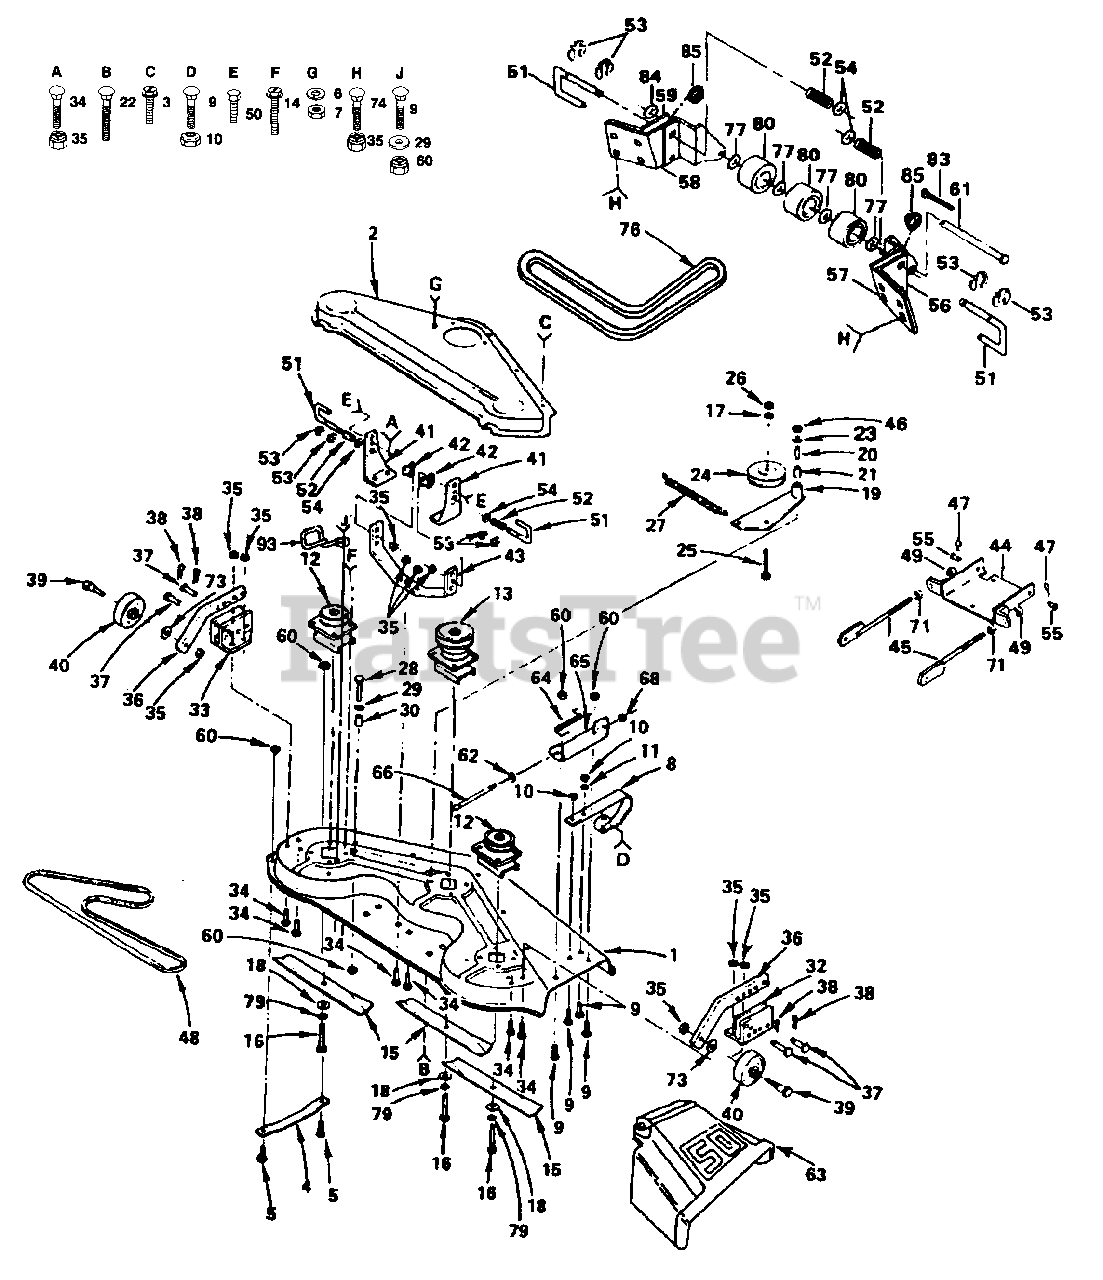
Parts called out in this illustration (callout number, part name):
1	Housing, Mower (AYP part number)
2	Cover, Drive, Deck (AYP part number)
3	Screw, Hex Washer Thd. Roll 5/16-18 x 1/2 (AYP part number)
4	Runner, L.H. (AYP part number)
5	Bolt, Carriage 5/16-18 x 5/8 (AYP part number)
6	Washer, Lock 5/16 (AYP part number)
7	Nut, Hex 5/16-18 (AYP part number)
8	Runner, R.H. (AYP part number)
9	Bolt, Carriage 5/16-18 x 3/4
10	Locknut 5/16-18 (AYP part number)
11	Washer 11/32 x 11/16 x 16 Gauge (AYP part number)
12	Mandrel, Secondary (AYP part number)
13	Mandrel, Primary (AYP part number)
14	Screw, Hex Washer Thd. Roll 3/8-16 x 3/4 (AYP part number)
16	Bolt, Hex 3/8-24 x 1-1/2 Grade 5 (AYP part number)
17	Washer, Lock 3/8 (AYP part number)
18	Washer 13/32 x 1-1/4 x 12 Gauge (AYP part number)
19	Arm Assembly, Idler (AYP part number)
20	Liner, Bearing (AYP part number)
21	Bearing (AYP part number)
22	Bolt, Carriage 5/16-18 x 1-1/4 Gr. 5 (AYP part number)
23	Washer 11/32 x 1-1/8 x 16 Gauge (AYP part number)
24	Pulley, Idler (AYP part number)
25	Bolt, Hex 3/8-16 x 1-1/2 (AYP part number)
26	Nut, Hex 3/8-16 (AYP part number)
27	Spring (AYP part number)
28	Bolt, Hex 5/16-18 x 1-1/4 Grade 5 (AYP part number)
29	Washer 11/32 x 3/4 x 16 Gauge (AYP part number)
30	Spacer Split (AYP part number)
32	Bracket, Ga. Wheel, R.H. (AYP part number)
33	Bracket, Ga. Wheel, L.H. (AYP part number)
34	Bolt, Carriage 3/8-16 x 3/4 (AYP part number)
35	Nut, Crownlock 3/8-16
36	Bar, Ga. Wheel (AYP part number)
37	Pin, Clevis (AYP part number)
38	Retainer, Spring (AYP part number)
39	Bolt, Shoulder (AYP part number)
40	Wheel, Gauge (AYP part number)
41	Bracket, Suspension (AYP part number)
42	Spacer (AYP part number)
43	Brace, Suspension (AYP part number)
44	Plate Assembly, Mower Suspension (AYP part number)
45	Bracket, Suspension (AYP part number)
46	Nut, Hex 5/16-18 (AYP part number)
47	Retainer, Spring (AYP part number)
48	V-Belt (AYP part number)
49	Nut, Crownlock 1/2-13 (AYP part number)
50	Bolt, Hex 3/8-16 x 1-3/8 (AYP part number)
51	Pin, Release (AYP part number)
52	Spring (AYP part number)
53	Ring, Klip (AYP part number)
54	Washer 17/32 x 5/8 x 16 Gauge (AYP part number)
55	Pin, Clevis (AYP part number)
56	Bracket, Outer, R.H. (AYP part number)
57	Bracket, Inner, R.H. (AYP part number)
58	Bracket, Inner, L.H. (AYP part number)
59	Bracket, Outer, L.H. (AYP part number)
60	Nut, Crownlock 5/16-18
61	Pin, Pivot (AYP part number)
62	Washer 11/32 x 5/8 x 16 Gauge (AYP part number)
63	Shield, Deflector (AYP part number)
64	Spring, Deflector (AYP part number)
65	Bracket, Deflector (AYP part number)
66	Rod, Hinge (AYP part number)
68	Nut, Push (AYP part number)
71	Nut, Hex 1/2-13 (AYP part number)
73	Washer 17/32 x 15/16 x 12 Gauge (AYP part number)
74	Bolt, Carriage 3/8-16 x 1 (AYP part number)
76	V-Belt (AYP part number)
77	Washer 15/32 x 1 x 10 Gauge (AYP part number)
79	Washer, Lock 3/8 (AYP part number)
80	Roller, Nose (AYP part number)
83	Spring, Retainer (AYP part number)
84	Washer 15/30 x 1 x 16 Gauge (AYP part number)
85	Spacer (AYP part number)
93	Keeper, L.H. (AYP part number)
